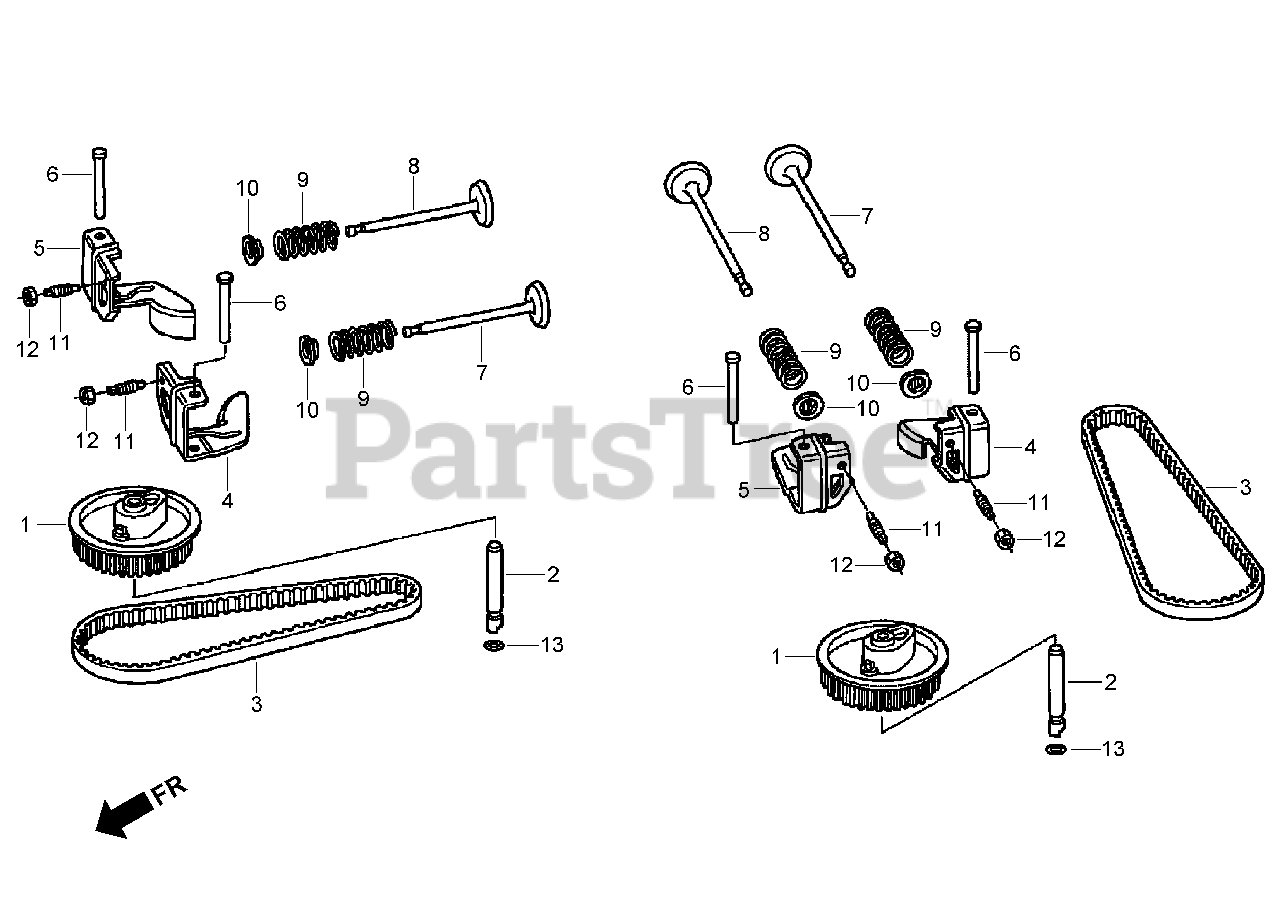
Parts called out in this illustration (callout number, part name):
1	PULLEY-CAMSHAFT
2	SHAFT-PULLEY, CAM
3	BELT-TIMING (97HU8 G-200)
4	ARM-VALVE ROCKER, INTAKE
5	ARM-VALVE ROCKER, EXHAUST
6	SHAFT-ARM, ROCKER
7	VALVE-INTAKE
8	VALVE-EXHAUST
9	Spring-Valve
10	RETAINER-SPRING, VALVE (INTAKE)
11	SCREW-ADJUSTING, TAPPET
12	NUT-ADJUSTING, TAPPET
13	O-RING (6.8X19) (ARAI)
